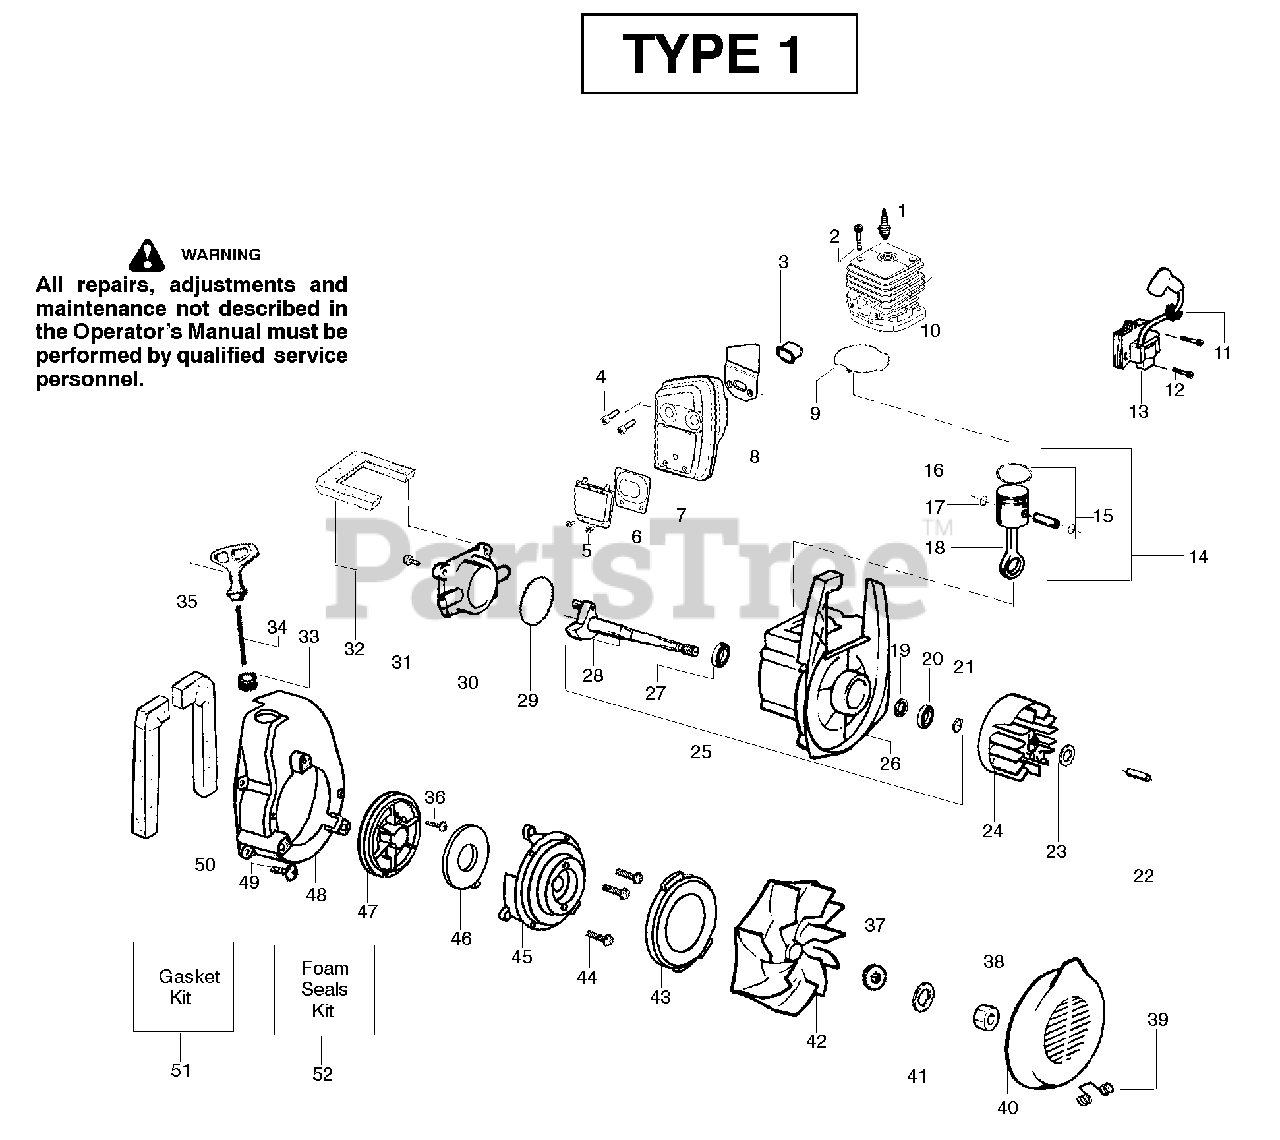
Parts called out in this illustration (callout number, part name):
1	Spark Plug (RCJ-6Y)
3	Insulator-Heat
4	Screw-Muffler-Internal
6	Kit-Spark Screen
7	Kit-Muffler
8	Gasket-Baffle (kit)
9	Gasket-Cylinder (kit)
10	Kit-Cylinder
11	Grommet-Ign. Module
12	Screw-Ignition Module
13	Ignition Module
14	Kit-Piston/Rod
15	Kit-Piston
16	Piston Ring
17	Retainer-Piston Pin
18	Assy-Connecting Rod
19	Seal-Crankcase
20	Bearing-Outer
21	Retainer Ring-C'chaft
22	Spacer-Flywheel
24	Assy-Flywheel
25	Assy-Crankcase/Crank shaft
26	Assy-Crankcase
27	Bearing-Inner
28	Assy-Crankshaft
29	O-ring-C/case (kit)
30	Cover-Crankcase
31	Screw
32	Foam-219mm (kit)
33	Eyelet-Flange
34	Kit-Rope
35	Handle-Starter
36	Screw-Rope
37	Washer-Belleville
39	Spring-Return Cover
40	Inlet Door
42	Kit-Impeller Assy.
43	Seal-Ring
45	Housing-Pulley
46	Spring-Starter
47	Kit-Starter Pulley
48	Fan Housing
49	Screw
50	Foam-182mm (kit)
51	Kit-Gasket
52	Kit-Foam Seals
